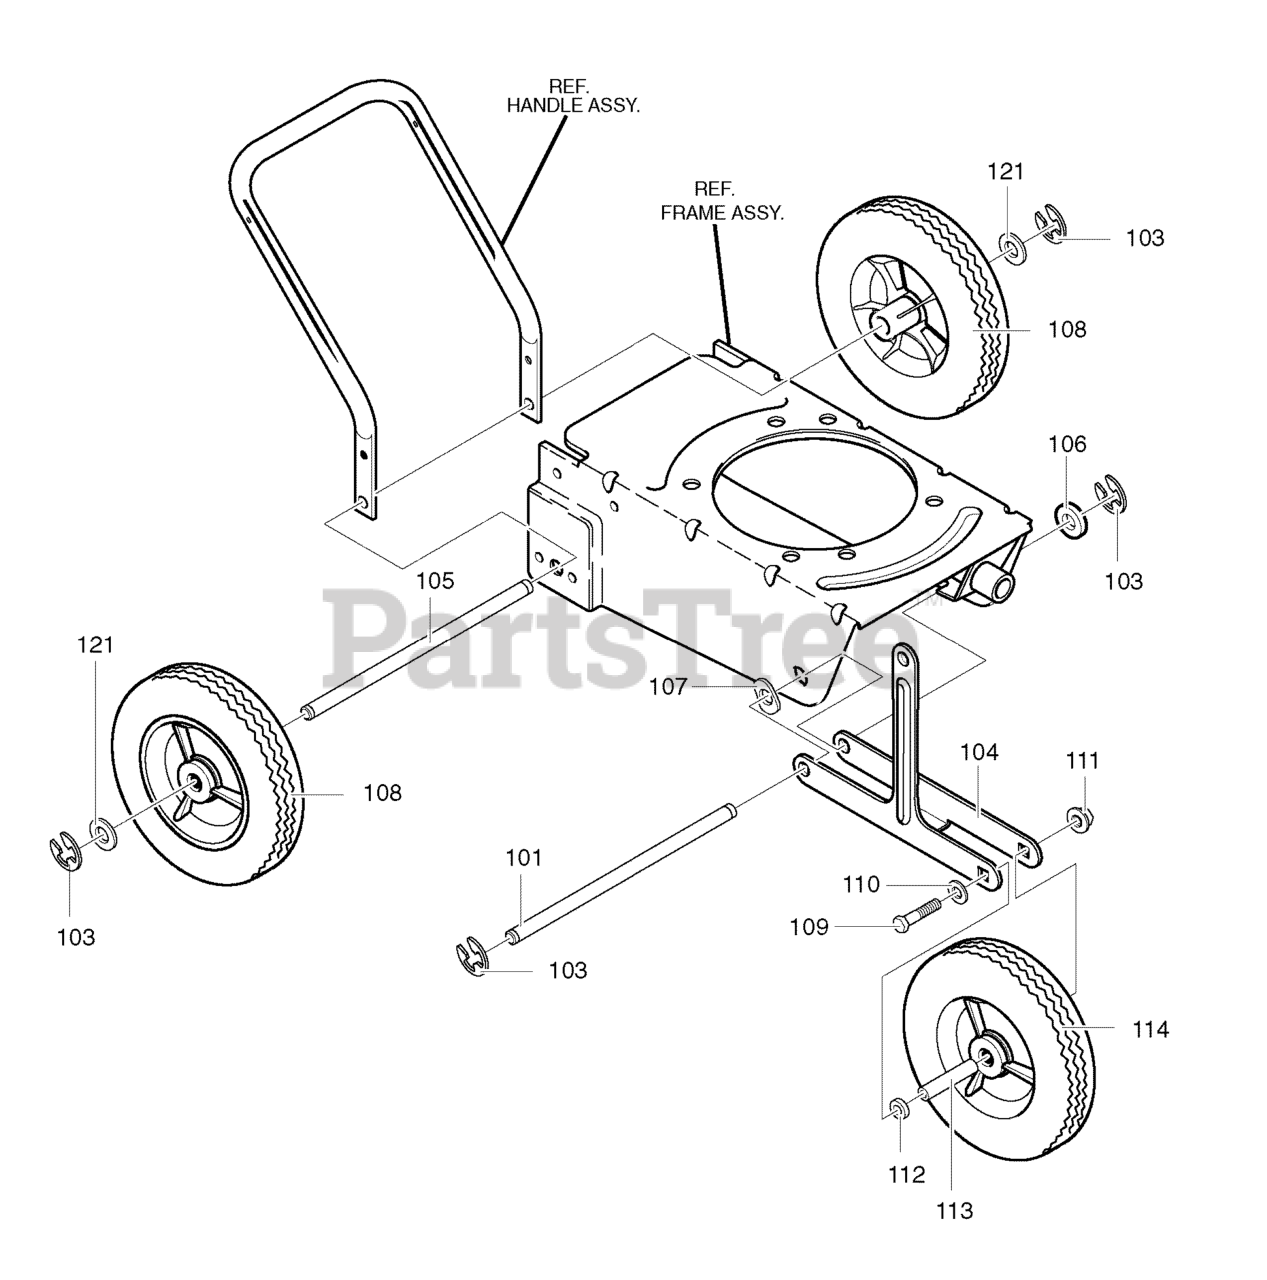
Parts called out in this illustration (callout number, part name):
101	ROD, Axle Front
103	E-RING, Ret
104	ARM, Front Wheel
105	ROD, Axle Rear
106	WASHER, Flat
107	WASHER, Spring
108	TIRE & RIM
110	WASHER, Flat
111	NUT, 5/16-18
112	WASHER, Nylon
113	SPACER, Sleeve
114	TIRE & RIM
121	WASHER, Flat
